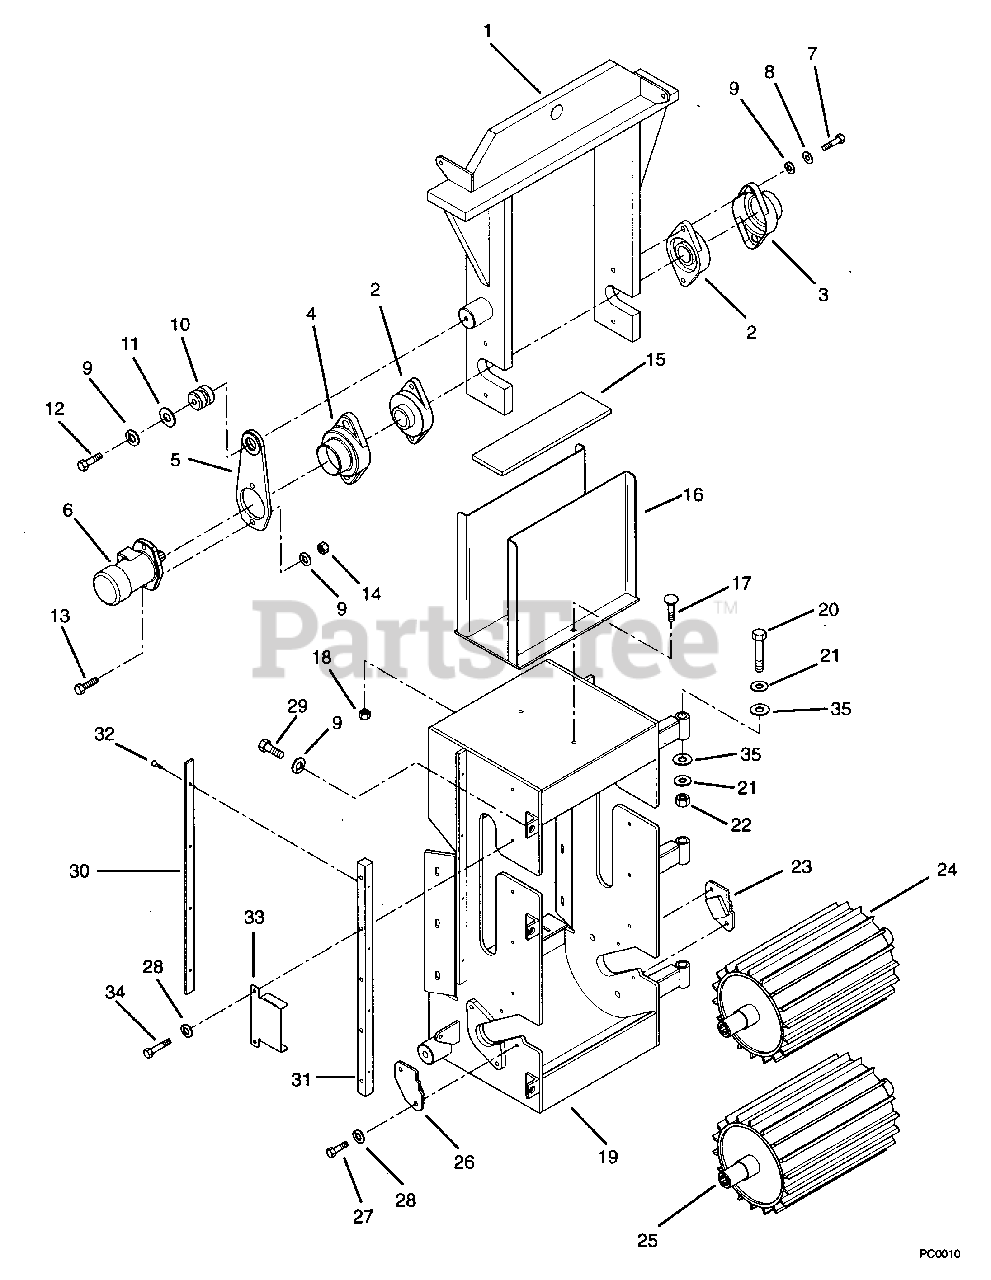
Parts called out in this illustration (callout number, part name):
1	Saddle Weldment
3	Bearing Cover
4	Shaft Cover
5	Torque Arm Weldment
6	Hydraulic Motor
7	Bolt-Hex .50-13 x 1.25 Grade 5
8	Washer-Flat-Steel .531 x 1.062 x .095
9	Washer-Lock .50 Reg.
10	Rubber Bushing
11	Washer
12	Bolt-Hex .50-13 x 3.00
13	Bolt-Hex .50-13 x 1.75 Grade 5
14	Nut .50-13
15	Rubber Stop
16	Saddle Guard Weldment
17	Bolt-Round Head Square Neck .38-16 x 1.25Grade 5
18	Nut-Lock .375-16
19	Feed Box Weldment
20	Bolt-Hex .75-10 x 5.00 Grade 2
21	Washer-Hardened-Thrust .758 x 1.23 x .031
22	Nut-Locking-Jam-Nylon .75-10
23	Cover Plate Weldment Left Hand
24	Roller Weldment - Top
25	Roller Weldment - Bottom
26	Cover Plate Weldment
27	Bolt-Hex .38-16 x .75 Grade 5
28	Washer-Lock .375 x .094
29	Bolt-Hex .50-13 x 1.00 Grade 8
30	Wear Strip
31	Front Guide
32	Screw-Socket Head .25-20 x .50 FlatCountersunk
33	Feed Box Guard
34	Bolt-Hex .38-16 x 1.50 Grade 5
35	Washer-Flat-Steel .755 x 1.375 x .125
